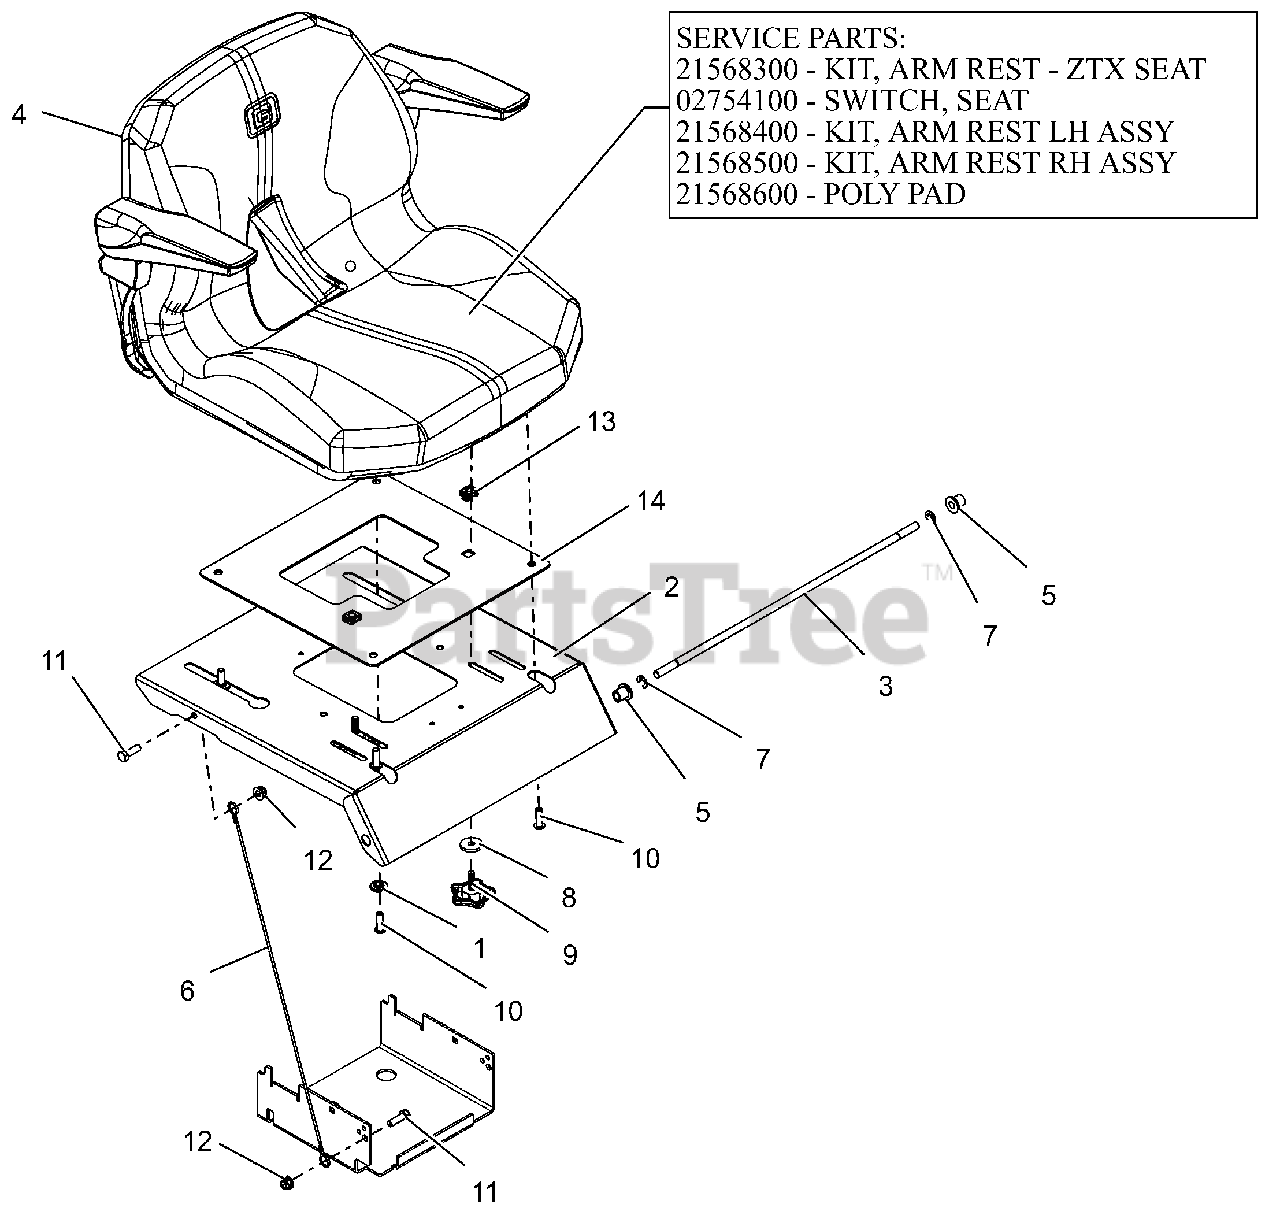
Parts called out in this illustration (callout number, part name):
1	BSHG, FLG .325X.499X.26X.88
2	PLATE, SEAT PLATE (SK100)
3	ROD, SEAT PIVOT
4	SEAT, ZTX 2019
4	KIT, ARM REST - ZTX SEAT
4	SWITCH- SNAP MTG N.O.
4	KIT, ARM REST LH ASSY
4	KIT, ARM REST RH ASSY
4	POLY PAD - ZTX SEAT
5	BSHG-FLG .38X.580X.667X.750
6	LANYARD, SEAT CABLE .093X19.5
7	RG-RTNG-EXT .375X.035 TYP E
8	WSHR, FLT .340X1.125X.135 ZCC
9	KNOB, WING STUDDED
10	BLT,SHCS-BTN .31-18X1.00 ZCC
11	BLT,HEX .31-18X1.00 G5 ZCC
12	NUT,NYL-FLG .31-18 GF ZCC
13	NUT, RETNR .312-18
14	PLATE, SEAT ADAPTOR (BLACK)
